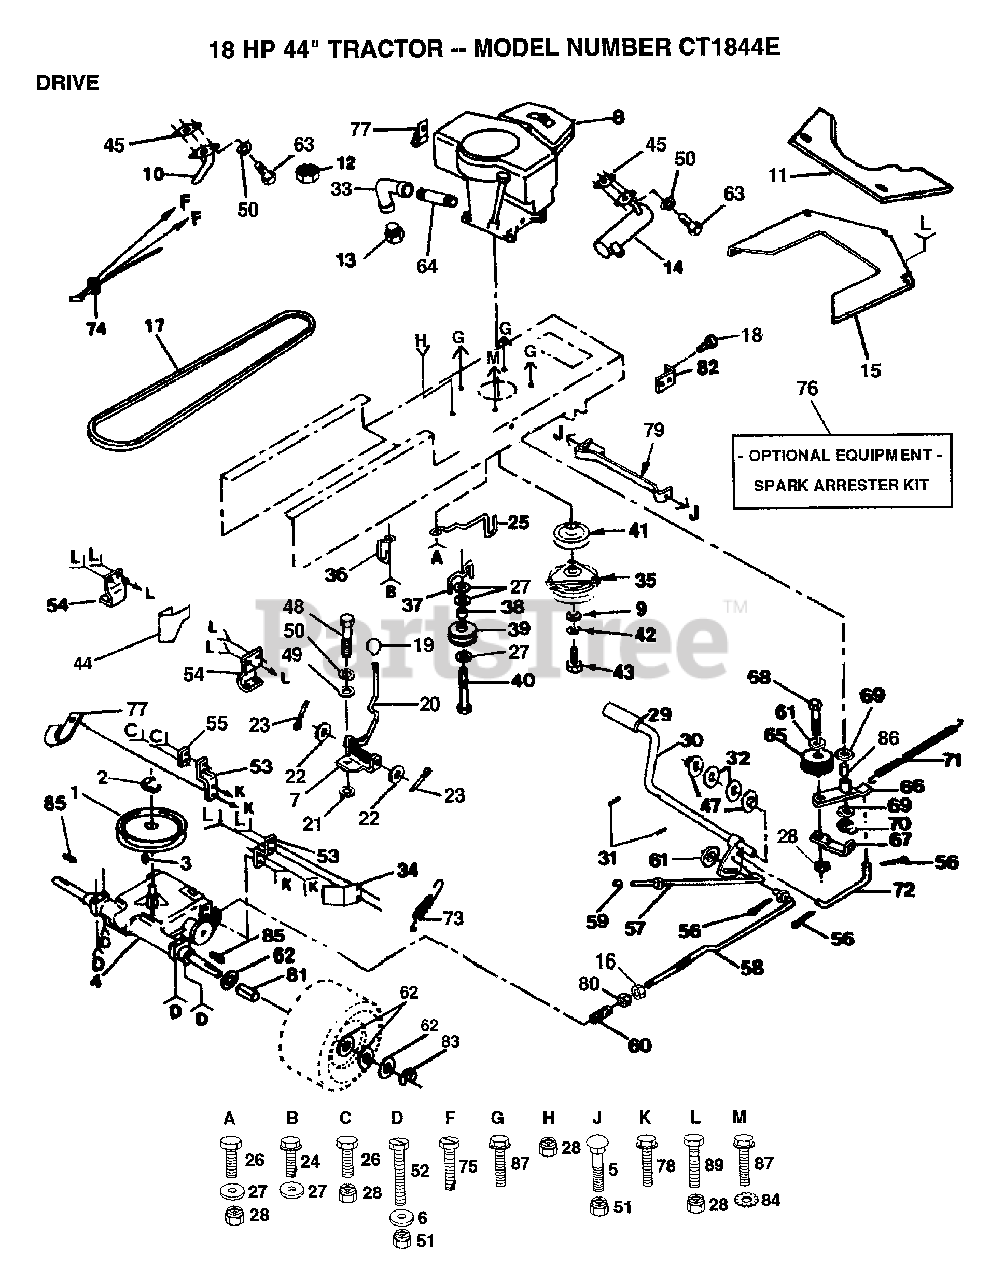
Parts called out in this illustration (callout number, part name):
1	PULLEY TRANSAXLE
2	RING
4	TRANSAXLE 6 SP
5	BOLT
6	WASHER
7	PLATE SHIFT LT
8	ENGINE B&S 18HP
9	WASHER
10	EXHAUST TUBE T
11	REAR BAFFLE T
12	NUT
15	SHIELD HEAT FRT
16	NUT
17	V BELT
18	SCREW
19	CONTROL KNOB LT
20	ROD SHIFTER T
21	WASH-SHFT PLT LT
22	WASHER
23	PIN COTTER 1/8
24	SCREW
25	KEEPER.BELT.ENG.L
26	BOLT
27	WASHER
29	PEDAL COVER T
32	WASHER LT
33	ELBOW
34	"KEEPER,BELT RH"
37	BELT KEEPER LT
38	SPACER T
39	PULLEY.IDLER.FLAT
40	BOLT
41	PULLEY ENGINE
42	LOCKWASHER
44	"KEEPER,BELT LH"
47	NYLON BEARING
49	WASHER LT
50	LOCKWASHER
52	BOLT HEX
53	STRAP TORQUE
54	BRACKET LT
55	PLATE-STRAP LT
56	COTTER PIN
57	BRAKE PARK ROD
58	ROD BRAKE
60	SPRING ROD LT
61	WASHER
62	WASHER
64	PIPE NIPPLE LT
66	ARM IDLER
67	RETAIN BELT
69	WASHER LT
70	KLIP RING
71	"SPRING, RETURN LT"
72	"LINK, CLUTCH T"
75	SCREW LT
76	SPARK ARREST KIT
77	CLIP T
78	SCREW
80	NUT
81	SPACER HYT
82	BRACKET LT
83	E RING HYT
84	LOCKWASHER
85	SQ KEY STD
86	"LY, BEARING"
87	SCREW LT
